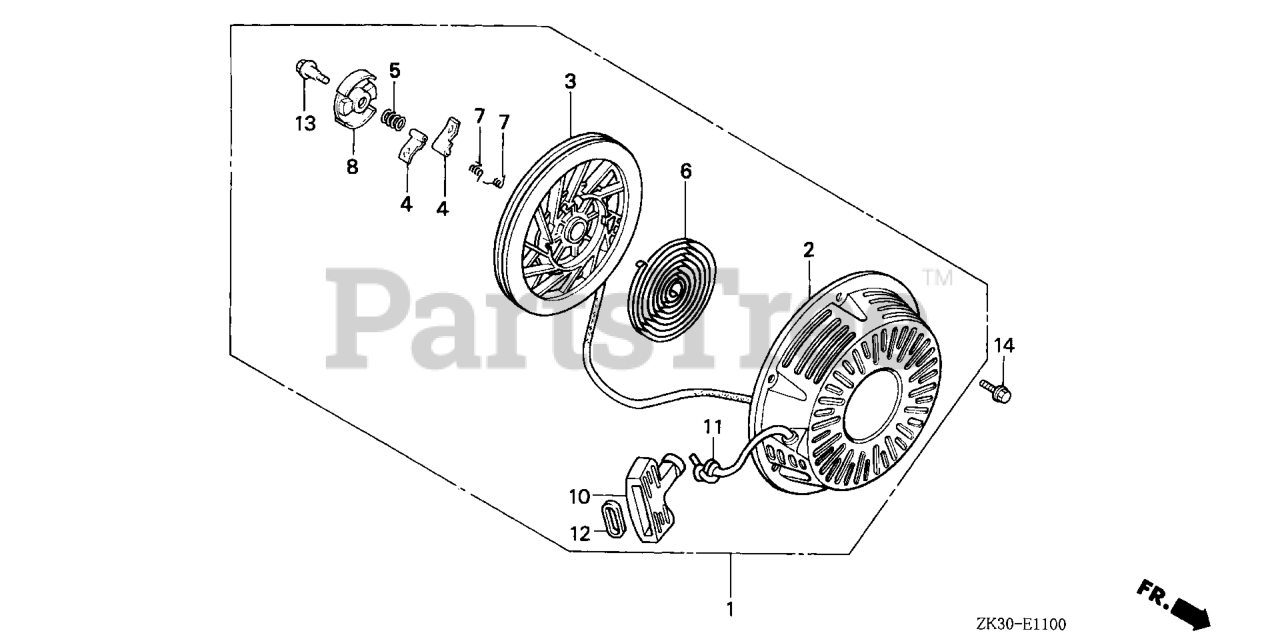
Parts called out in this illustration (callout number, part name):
1	STARTER ASSY., RECOIL *NH1* (BLACK)
2	CASE, RECOIL STARTER *NH1* (BLACK)
3	PULLEY, RECOIL STARTER
4	RATCHET, STARTER
5	SPRING, FRICTION
6	SPRING, STARTER RETURN
7	SPRING, RATCHET
8	RETAINER, SPRING
10	GRIP, STARTER
11	ROPE, RECOIL STARTER (#6X64") (N/A: USE P/N 08560-ZG921-11)
12	GRIP, REINFORCEMENT
13	SCREW, CENTER
14	BOLT, FLANGE (6X8)
